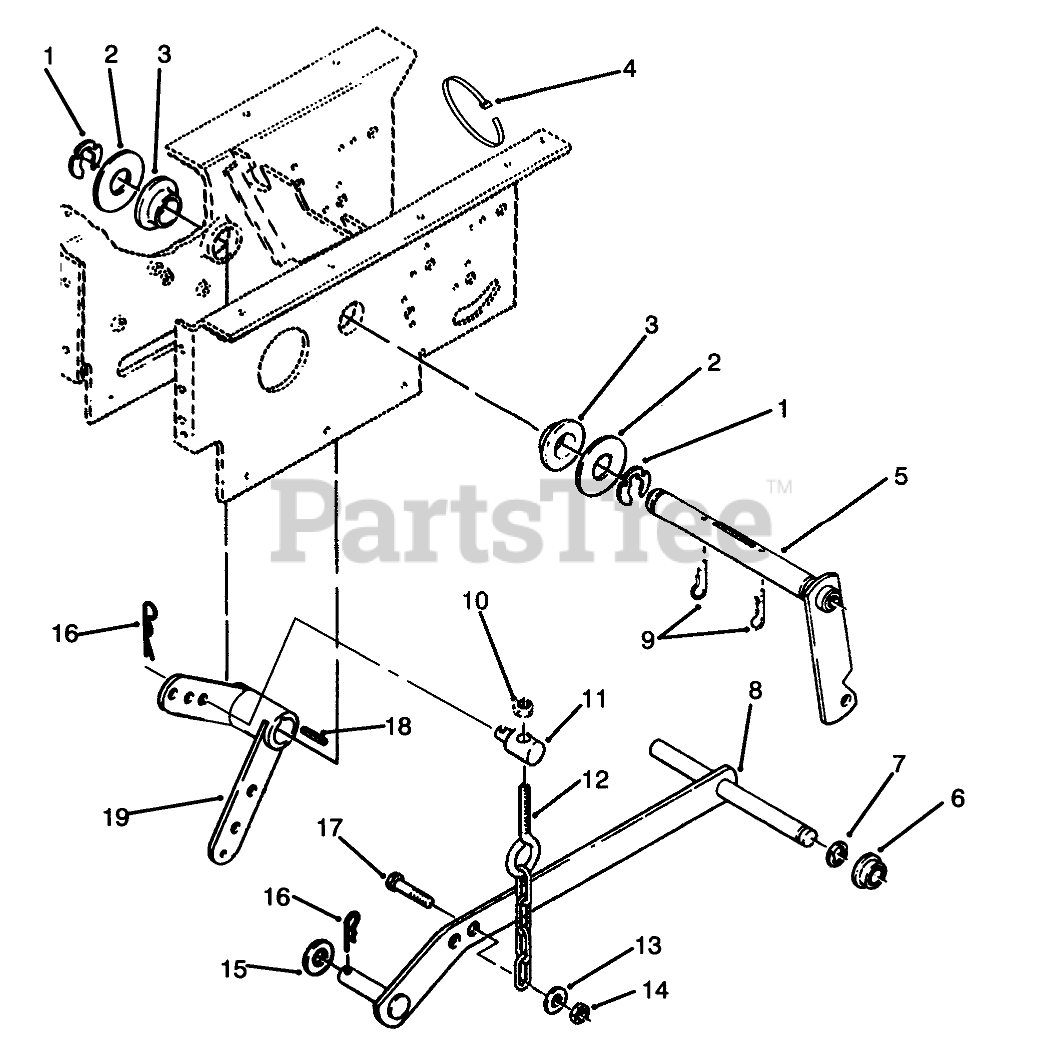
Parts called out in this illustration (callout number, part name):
1	PIN-SPRING
2	WASHER-FLAT
3	BEARING-FLANGE
4	TIE-CABLE
5	WLDMT-LIFT ARM
6	BUSHING
7	RING-RETAINING, EXTERNAL
8	Bar-Lift
9	Pin-Cotter
10	NUT-LOCK, NI
11	TRUNNION-LIFT
12	CHAIN-LIFT
13	WASHER-PLAIN
14	NUT-LOCK, NI
15	WASHER-FLAT
16	Hairpin Cotter
17	SCREW-HH
18	KEY-SQUARE
19	LIFT LEVER ASM
